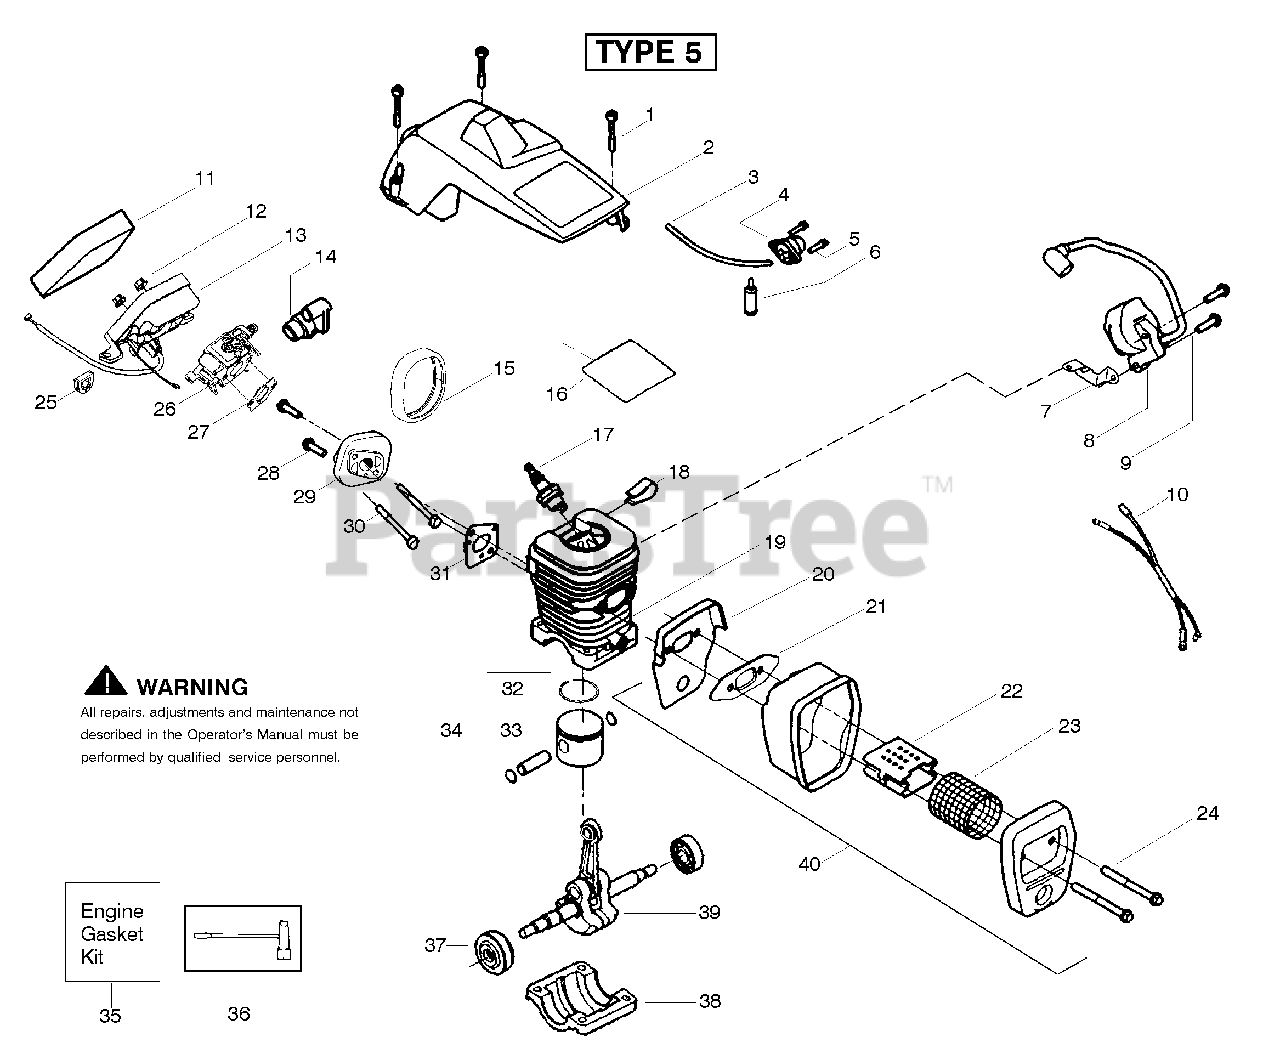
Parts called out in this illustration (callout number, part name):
2	Assy-Cylinder Shield
3	Kit-Fuel Line (Small)
4	Kit-Purge Bulb
6	Assy-Fuel Pick-up
7	Strap-Ground
8	Ignition Module
10	Assy-Wire Harness
11	Foam- Air Filter
13	Assy- Air Box
14	Grommet-Carb Adjust
15	Seal-Carb Adapter
16	Reflector-Heat
17	Spark Plug (RCJ-7Y)
18	Clip-High Tension Lead
19	Cylinder
20	Backplate-Muffler
21	Gasket-Muffler(kit)
22	Diffuser-Muffler
23	Screen-Spark
24	Bolt-Muffler
25	Grommet-Throttle Cable
26	Kit-Carburetor Zama (W-20)
26	Kit-Carburetor Walbro (WT-662)
27	Gasket-Carb. (kit)
29	Carb. Adapter
31	Gasket- Adaptor(kit)
32	Ring-Piston
33	Retainer-Piston Pin
34	Kit-Piston
35	Kit-Engine Gasket
36	Scrench
37	Assy-Seal & Bearing
38	Cap-Crankcase
39	Assy-Crankshaft
40	Assy-Muffler
